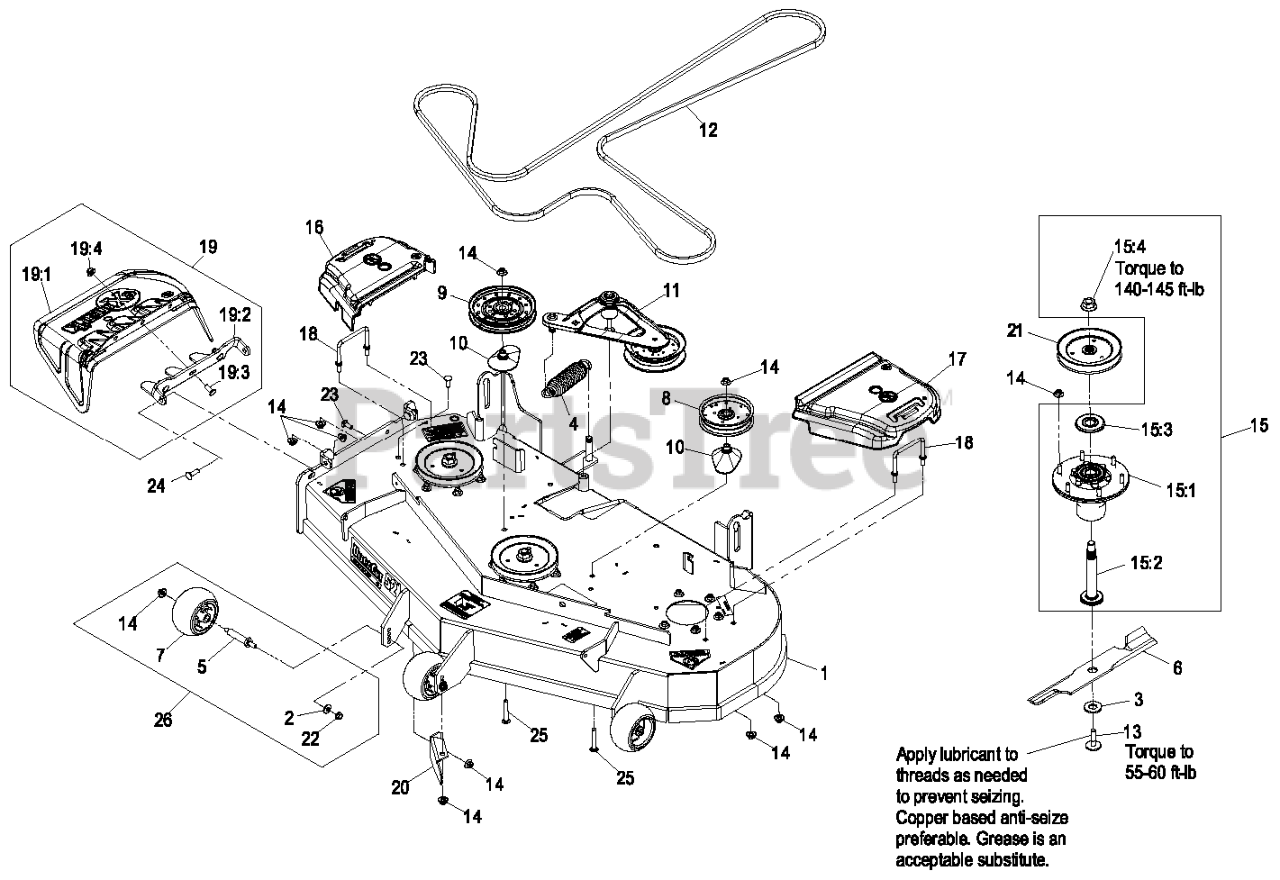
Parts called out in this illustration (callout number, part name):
1	ASM,524 DECK WITH DECALS
2	WASHER-BELLEVILLE
3	WASHER-BLADE DRIVE
7	ROLLER-SCALP, ANTI
8	PULLEY-IDLER
10	SPACER-PULLEY
13	BOLT-BLADE, SEM
14	Nut-Nyloc 3/8-16 Flg
15:1	ASM,CUTTER HSG WITH BEARI
15:2	SPINDLE,HEX PILOT 5.5" DE
15:3	GUARD,BEARING TOP .989
15:4	NUT-FLANGE
16	COVER-BELT, RH
17	COVER-BELT, LH
18	WIREFORM-COVER
19	ASM,DISCHARGE CHUTE
19:1	CHUTE,DISCHARGE
19:2	BRACKET,DISCHARGE CHUTE
19:3	SCREW-CARR
19:4	Nut-Nyloc 3/8-16 Flg
20	BAFFLE,DISCHARGE 52/60
21	SHEAVE,BLADE DRIVE 6.50
22	NUT-HHF, WHIZ
23	SCREW-CARR
24	Bolt-Carriage 3/8-16 X 1 1/4
25	SCREW-CARR
27	Asm, Complete Deck
